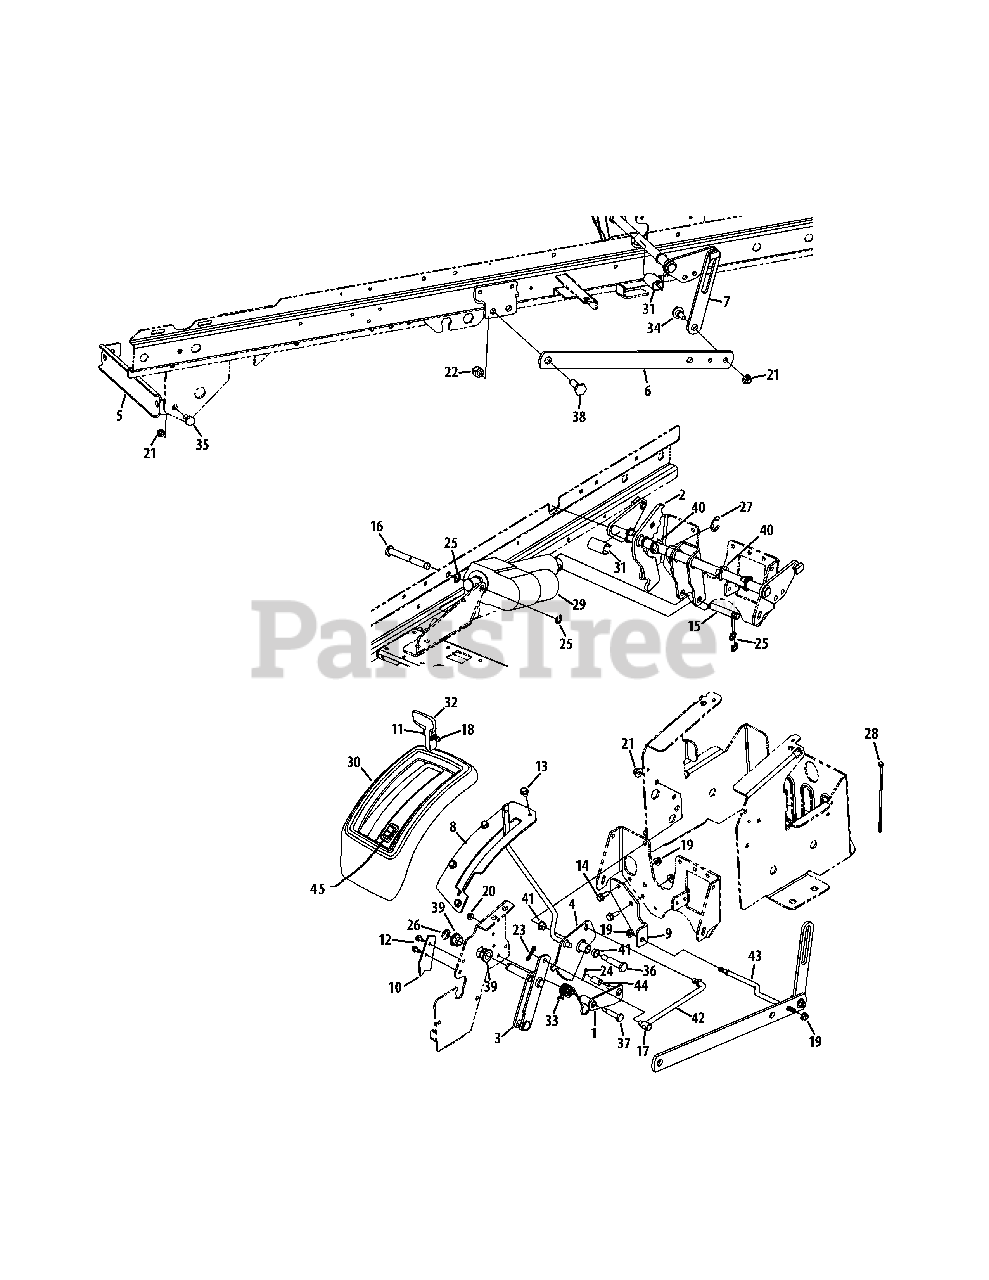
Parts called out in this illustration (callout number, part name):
1	Hub Lift Assembly
2	Electric Shift Assembly
3	Deck Height Adjustment Weldment
4	Lift Lever Bracket Assembly
5	Front Hanger Bracket
7	Lift Link Plate
9	Sway Bar Mount Bracket
10	Bearing Stop Plate
11	Machine Screw, #10-24 x .625
12	Hex Washer Screw, 1/4-20 x .500
13	Hex Washer Screw, 5/16-18 x .625
14	Hex Washer Screw, 5/16-18 x .875
15	PIN, .50 x 3.5
16	Clevis Pin, .50 x 4.0
17	Ferrule, 3/8-24 x .375
18	Hex Lock Nut, #10-24
19	Flange Lock Nut, 5/16-18
20	Flange Lock Nut, 1/4-20
21	Flange Lock Nut, 3/8-16
22	Hex Lock Nut, 1/2-13
23	Bow-Tie Cotter Pin, 72
24	Cotter Pin, .125 x .75
25	E-Ring, .500
26	E-Ring, .625
27	E-Ring, .875
28	Cable Tie, 3/16 x .05 x 7.4
29	Lift Actuator
30	Lift Cover
32	Electric Lift Knob
33	Torsion Spring
34	Shoulder Screw, 3/8-16 x .562 x .360
35	Shoulder Screw, 1/2 x .29
36	Shoulder Screw, .498 x 1.635
37	Shoulder Screw, .374 x 1.375
38	Shoulder Screw, 1/2-13 x .625 x .36
39	Hex Flange Bearing
40	Hex Flange Bearing, .78
41	Flange Bearing, .500 x .34
42	Electric Lift Rod Adjuster
43	Anti-Sway Deck Rod
44	Spacer, .35 x .5 x .851
45	Lift Switch
